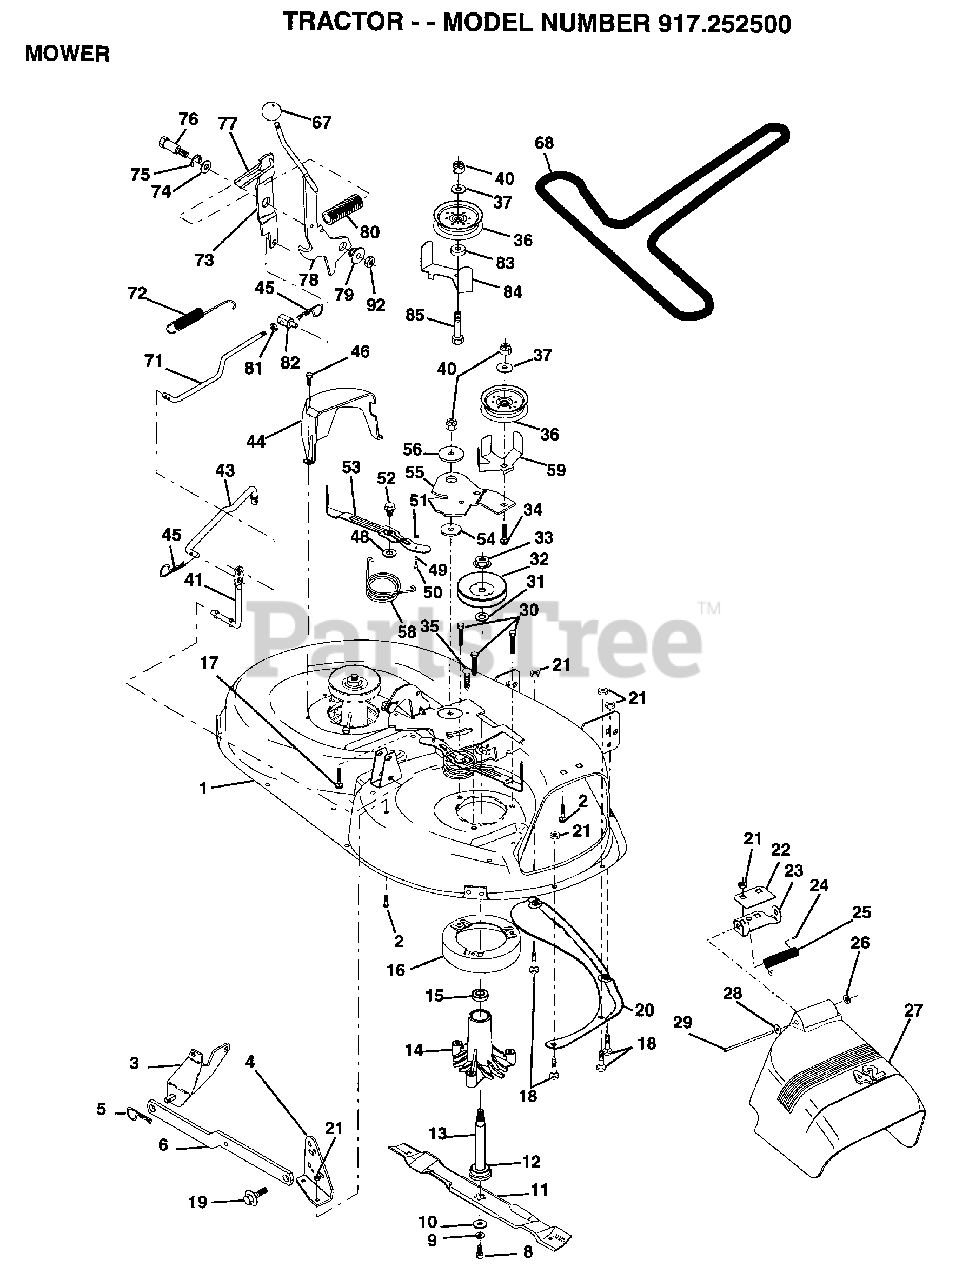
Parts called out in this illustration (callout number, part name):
1	DECK.WELD.42.
3	BRKT ASM SWAY BAR
4	BRKT DECK SW BAR
5	RETAINER RING
8	BLADE BOLT
10	WASHER.HARD.BLADE
11	"BLADE.42"" MULCHER"
12	BEARING.BALL
14	HSG ASM MANDREL
15	BEARING
16	STRIPPER RND MWR
17	BOLT RDHD 3/8-16
18	BOLT
19	BOLT SHD 5/16-18
22	STIFFENER BRKT
23	DEFLECTOR BRKT
24	CAP-SLEEVE LT
25	SPRING TORSION
26	NUT PUSH M
27	DEFLECTOR.SHIELD
28	WASHER
29	HINGE ROD
31	WASHER
35	XMAS TREE FASTNER
36	FLAT IDLER PULLEY
37	WASHER
41	PIVOT ROD
43	ROD CLUTCH W/NIBS
44	GUARD MAND LH BLK
46	SCREW.1/4-20X5/8
48	HARD SMALL WASHER
50	SHOULDER BOLT
52	BOLT.SHLD.5/16-18
53	BRAKE PAD ARM ASM
54	HARDENED WASHER
56	SPACER RETAINER
58	SPRING TORSN BRAK
59	GUARD IDLER TUV
67	KNOB T(3/8 HOLE)
68	BELT.V.T-PATH
71	ROD CLUTCH 38/42
72	RETURN SPRING
73	CLUTCH ARM SECOND
74	WASHER
75	RING
76	SHOULDER BOLT
77	SPRING KEEPER
79	BUSHING
81	NUT
82	TRUNION ADJ
83	WASHER
85	BOLT CARRIAGE
92	NUT
